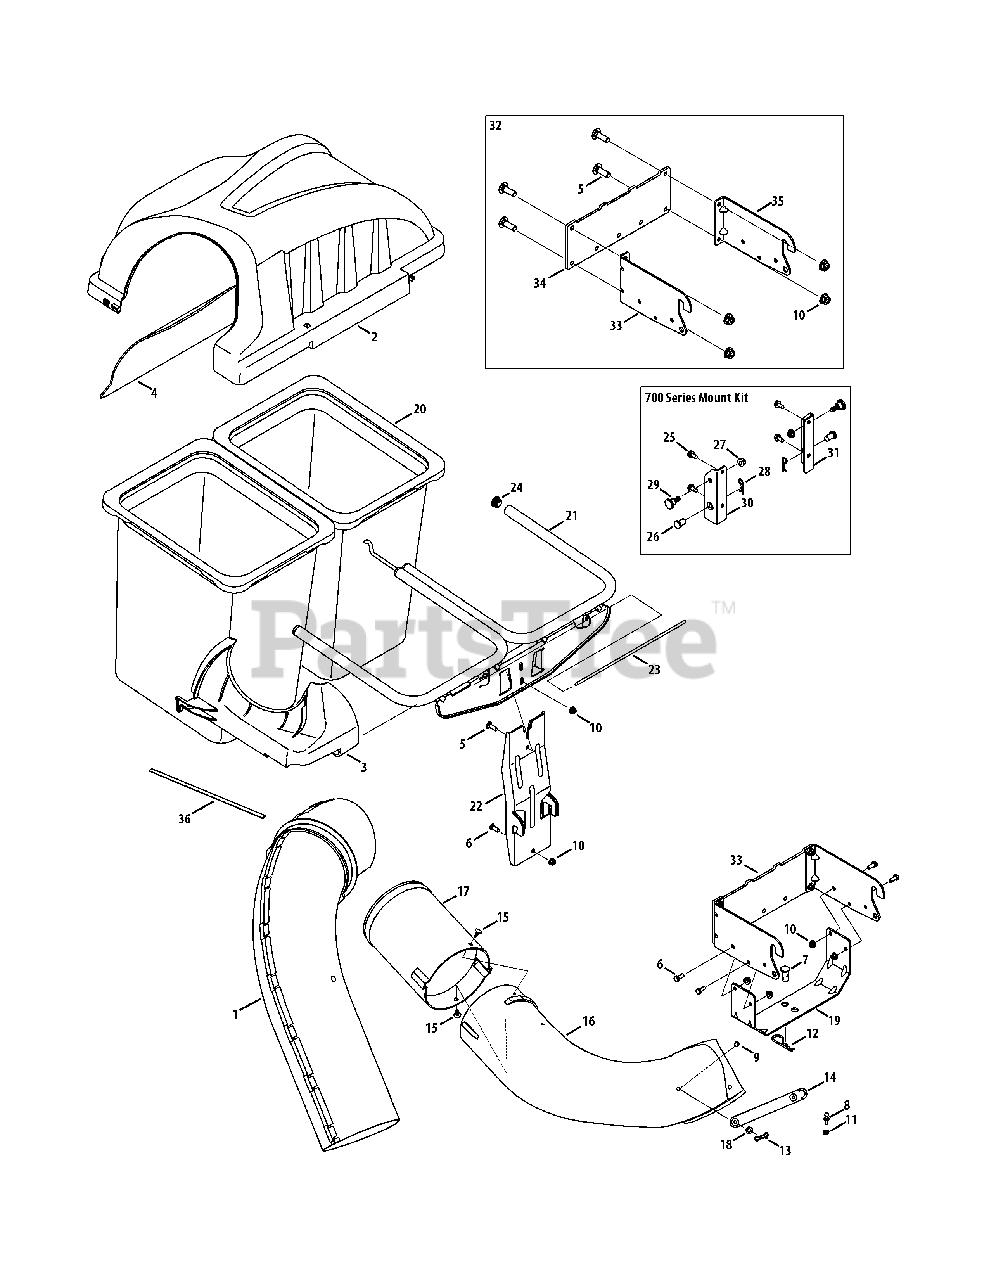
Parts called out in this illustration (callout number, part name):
1	Upper Chute Assembly
2	Double Bagger Cover Assembly
3	Upper Chute Support
4	Bagger Cover Screen
5	Carriage Screw, 5/16-18 x 1.00"
6	Hex Head Screw, 5/16-18 x .75"
7	Clevis Pin, .62" Dia.
8	Grass-catcher Pin, 1/4-20
9	Clevis Pin, 5/16 x .75 Lg.
10	Flange Lock Nut, 5/16-18
11	Flange Lock Nut, 1/4-20
12	Internal Cotter Pin, .148 x 3.00
13	Bow-Tie Cotter Pin, 72
14	Chute Strap, 6.00 Lg.
15	Ratchet Clip, .250
16	Discharge Chute Elbow, 38"/42" Deck
17	Bagger Chute Adapter, 8 In.
18	Flat Washer, .344 x .62 x .033
20	Grass-bag Assembly
21	Double Bag Support Assembly
22	Vertical Support Bracket
23	Cover Hinge Pin
25	Tap Screw, 5/16-18 x .750
26	Clevis Pin, .50 x .78 Lg.
27	Flange Lock Nut, 3/8-16
28	Click Pin, .092 x 1.64 Lg.
29	Shoulder Screw, .625 x .412
30	Mounting Bracket, RH
31	Mounting Bracket, LH
32	Hitch Bracket Assembly (Incl. 33-35)
33	Hitch Bracket, RH
34	Rear Attachment Bracket
35	Hitch Bracket, LH
36	Self-Adhesive Foam Strip
